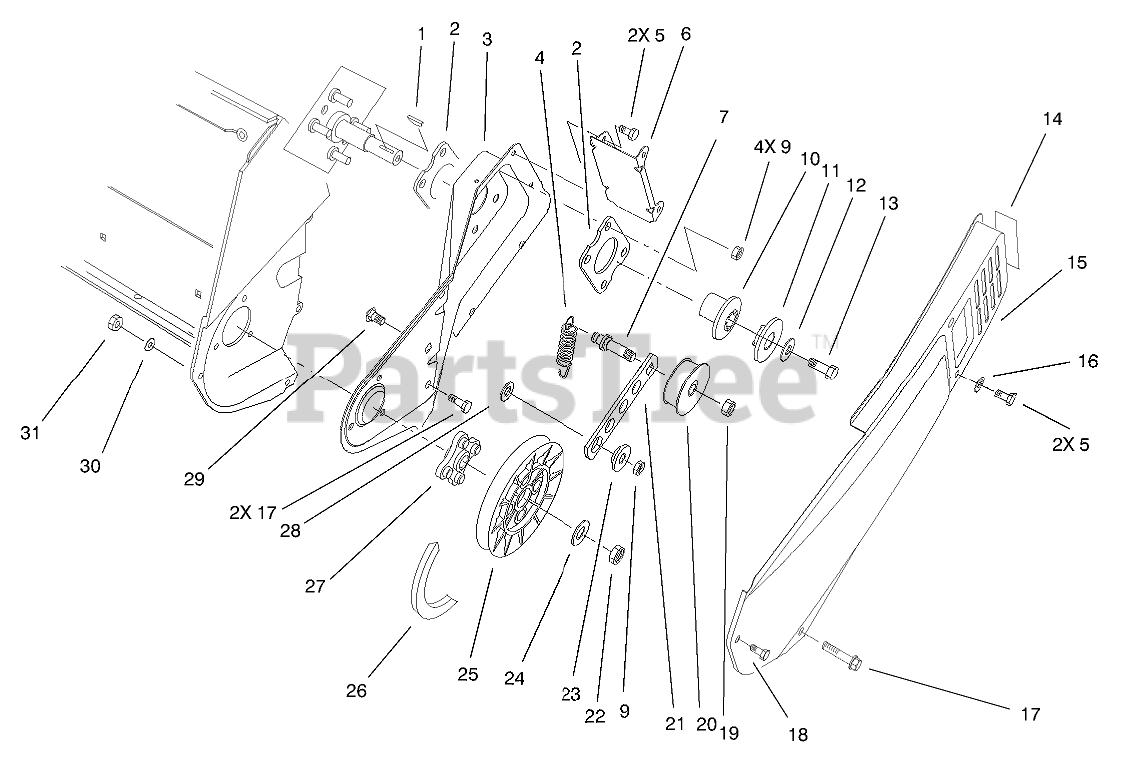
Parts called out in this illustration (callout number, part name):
1	KEY-WOODRUFF
2	PLATE-ENGINE
3	SIDEPLATE-LH
4	SPRING-EXTENSION
5	SCREW-HWH
6	BRACKET-COVER, BELT
7	PIN-IDLER
9	NUT-LOCK, NI
10	Hub-HALF SHEAVE
11	CAP-HALF SHEAVE
12	WASHER-FLAT
13	SCREW-HH
14	DECAL-WARNING
15	COVER-BELT
16	WASHER-FLAT
17	SCREW-PLASTIC
19	NUT-LOCK, NI
20	PULLEY-IDLER
21	ARM-IDLER
22	NUT-LOCK, NI
23	BUSHING-IDLER
24	WASHER-FLAT
25	PULLEY-DRIVEN
26	V-BELT
28	WASHER
29	SCREW-CARR
30	WASHER-FLAT
31	NUT-LOCK, NI
